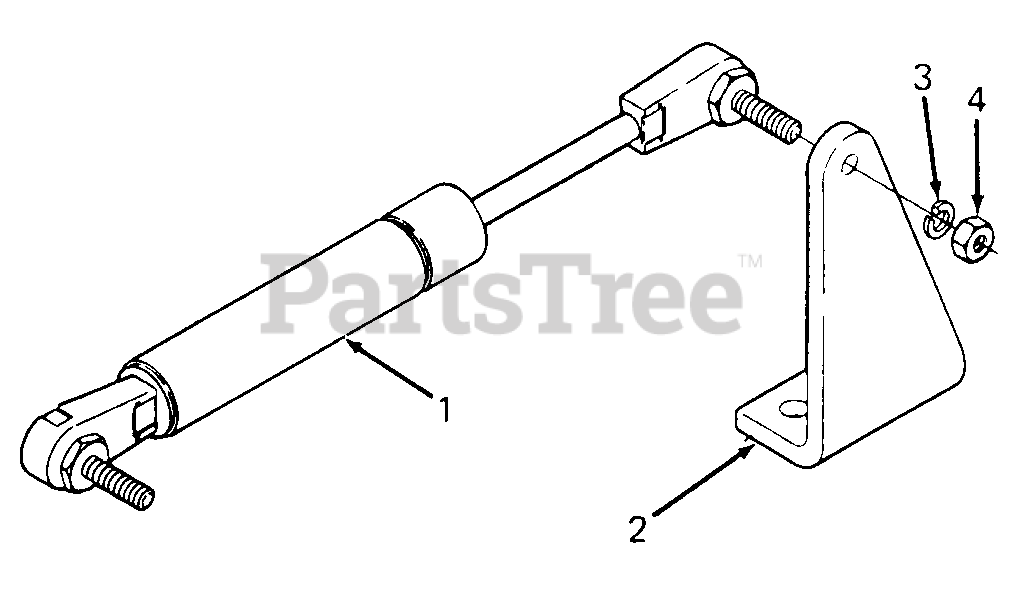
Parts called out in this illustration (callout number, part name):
1	Spring Assy, Gas
2	Bracket, Spring
3	Washer, Lock 5/16
4	Nut, 5/16-18 GR 5
